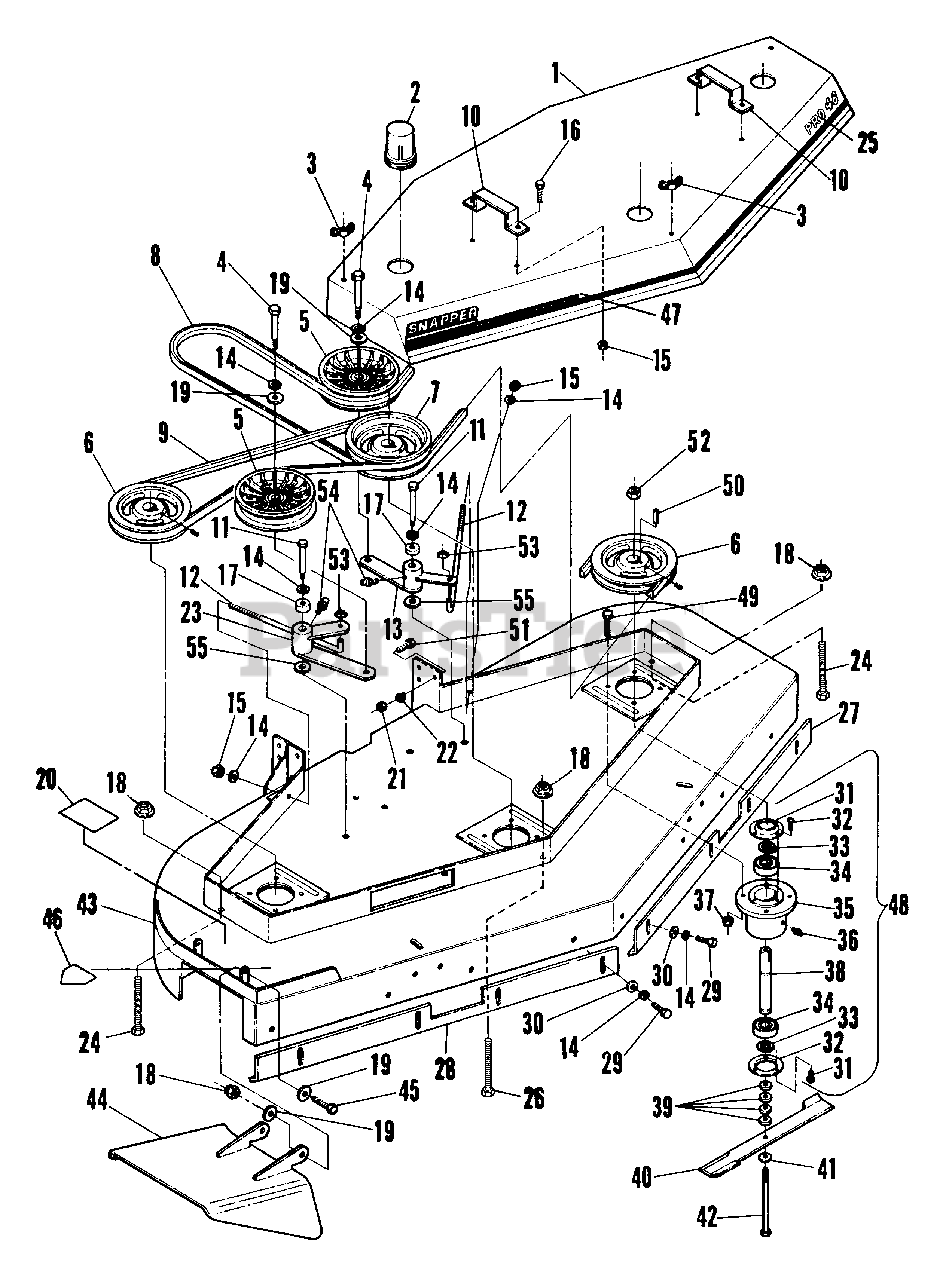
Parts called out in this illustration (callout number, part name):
1	HOOD w/DECALS 48
2	CAP, Spindle
3	NUT, 3/8"-16 Wing
4	SCREW, 3/8"-16 x 1 3/4" Hex Head Cap
5	PULLEY, Idler
6	PULLEY, w/Set Screws
7	PULLEY, Double w/Set Screws
8	BELT, Engine to Deck
9	BELT, Cutter Spindle
10	HANDLE, Hood
11	SCREW, 3/8"-26 x 3 1/4" Gr. 5 Hex Head Cap
12	ROD, Belt Adjusting
13	ARM, Engine to Deck Idler Weldment
14	WASHER, 3/8" Lock
15	NUT, 1/4"-20 Nylon Ring Hex Lock
16	SCREW, 1/4"-20 x 5/8" Gr. 5 Hex Head Cap
17	SPACER, Pivot
18	NUT, 3/8"-16 Hex Flange Lock
19	WASHER, 3/8" Flat
20	DECAL, Caution
21	NUT, 1/2"-13 Hex
22	WASHER, 1/2" Lock
23	ARM, Blade to Blade Idler Weldment
24	TAP BOLT, 3/8" x 5"
25	DECAL, Pro 48
26	TAP BOLT, 3/8" x 4"
27	SKIRT, Front L.H.
28	SKIRT, Front R.H.
29	SCREW, 3/8"-16 x 3/4" Gr. 5 Hex Head Cap
30	WASHER, Flat
31	CAP, Cutter Housing
32	SCREW, #10-24 x 1/2" Self-Tapping
33	RING, Retaining
34	BEARING, Single Seal
35	HOUSING, Cutter
36	ZERK, 1/8" NPT
37	NUT, 3/8"-16 Nylon Ring Hex
38	SPINDLE, Cutter
39	SPACER, Blade
40	BLADE, 16 1/2" High Lift
41	WASHER, 5/8" Bevel
42	SCREW, 5/8"-18 x 8 1/2" Gr. 5 Hex Head Cap
43	DECK, 48" Mowing
44	DEFLECTOR, Chute
45	SCREW, 3/8"-16 x 1" Gr. 5 Hex Head Cap
46	WARNING DECAL
47	DECAL, 48 Hood
48	HOUSING, Assembly Cutter
49	SCREW, 3/8"-16 x 1 1/4" Hex Head Cap
50	KEY, Spindle
51	BOLT, 1/2"-13 x 1 1/4" Hex Flange Lock
52	NUT, 5/8"-18 Hex
53	RETAINER, 3/8"
54	ZERK, Fitting
55	BUSHING, 1" x 14 Ga. Machine
